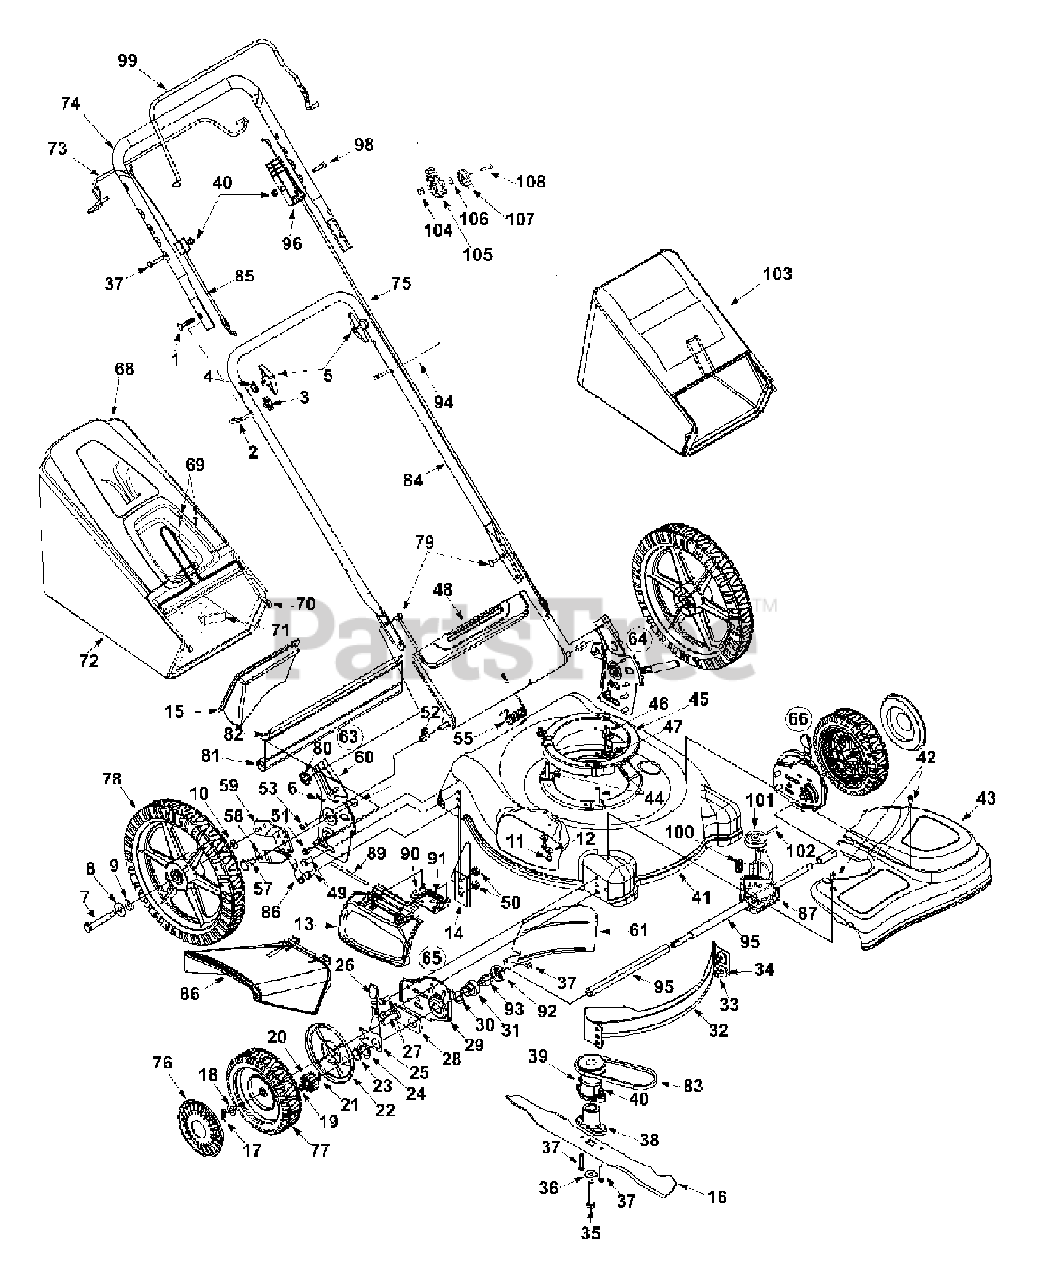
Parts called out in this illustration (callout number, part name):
1	Carriage Bolt
2	Rope Guide
3	Wing Nut
4	Saddle Washer
5	Handle Knob
6	Hairpin Clip
7	Shoulder Screw
8	Flat Washer .510 I.D. x 1.373 O.D.
9	Spring Wash. .500 I.D. x 1.00 O.D.
10	Bell Washer .375 I.D. x .870 O.D.
11	Tapp Screw 1/4-20 x .500
12	Bell Wash. .265 I.D. x .75 O.D.
13	Mulching Plug (Hinged)
15	Mulching Plug
16	Mulching Blade w/Star
16	Standard Blade
17	Hairpin Clip
18	Flat Washer
19	Snap Ring
20	Gear 14T RH
21	Dowel Pin
22	Wheel Dust Cap
23	Snap Ring
24	Washer DD 1.5" O.D.
25	Front Lever RH
26	Knob
27	Hex Screw
28	Pivot Plate Assembly
30	Wave Washer
31	Bearing Support
34	Bell Washer
35	Hex Bolt
36	Bell Washer
37	Hex Screw 1/4-20 x 1.5"
38	Blade Adapter
39	Drive Pulley
40	Hex Lock Nut
43	Transmission Cover
43	Transmission Cover Black
44	TT Screw
45	Engine Spacer Assembly
46	Belt Keeper Pin
47	Hex Nut 1/4-20
50	Flange L-Nut 3/8-16
51	AB Tap Screw 1/4-14 x .625"
52	Spacer
53	Pan Hd. Screw 1/4-20 x .5"
54	Pivot Rod
55	Torsion Spring
56	Foam Grip
57	Shoulder Screw
58	Spring Lever
59	Pivot Bar LH
59	Pivot Bar RH
60	Handle Bracket Assembly RH
62	Scr. AB 1/4-14 x 0.625"
65	Height Adjuster Ass'y Comp. RH
66	Height Adjuster Ass'y Comp. LH
68	Hardtop Cover
69	AB Screw 1/4-14
75	Control Cable 39" Lg.
76	Hub Cap 3.5 Dia.
76	Hub Cap 5.5 Dia.
77	Wheel 8 x 2 Bar Tread
77	Wheel 8 x 2 Zag Tread
78	Wheel 14 x 2 Bar Tread
78	Wheel 14 x 2 Zap Tread
79	Carriage Bolt
80	Wing Nut
81	Trail Shield
82	Wire
83	V-Belt
85	Drive Cable
86	Chute Deflector
87	Transmission Assembly Comp.
88	TT-Scr. 5/16-18
89	Hinge Pin
91	Torsion Spring
92	Bearing Retainer
93	Bearing Sleeve .50 I.D.
94	Cable Tie
95	Sleeve Spacer RH
96	Throttle Housing
97	Hex L-Nut 1/4-20
98	C-Sunk Screw 1/4-20
100	Belt Tension Spring
101	Input Pulley
102	Roll Pin
103	Grassbag
104	Hex L-Nut 1/4-20
105	Throttle
106	Curved Spring Washer
107	Throttle Lever
108	Oval C-Sunk Screw 1/4-20 x 1.825
